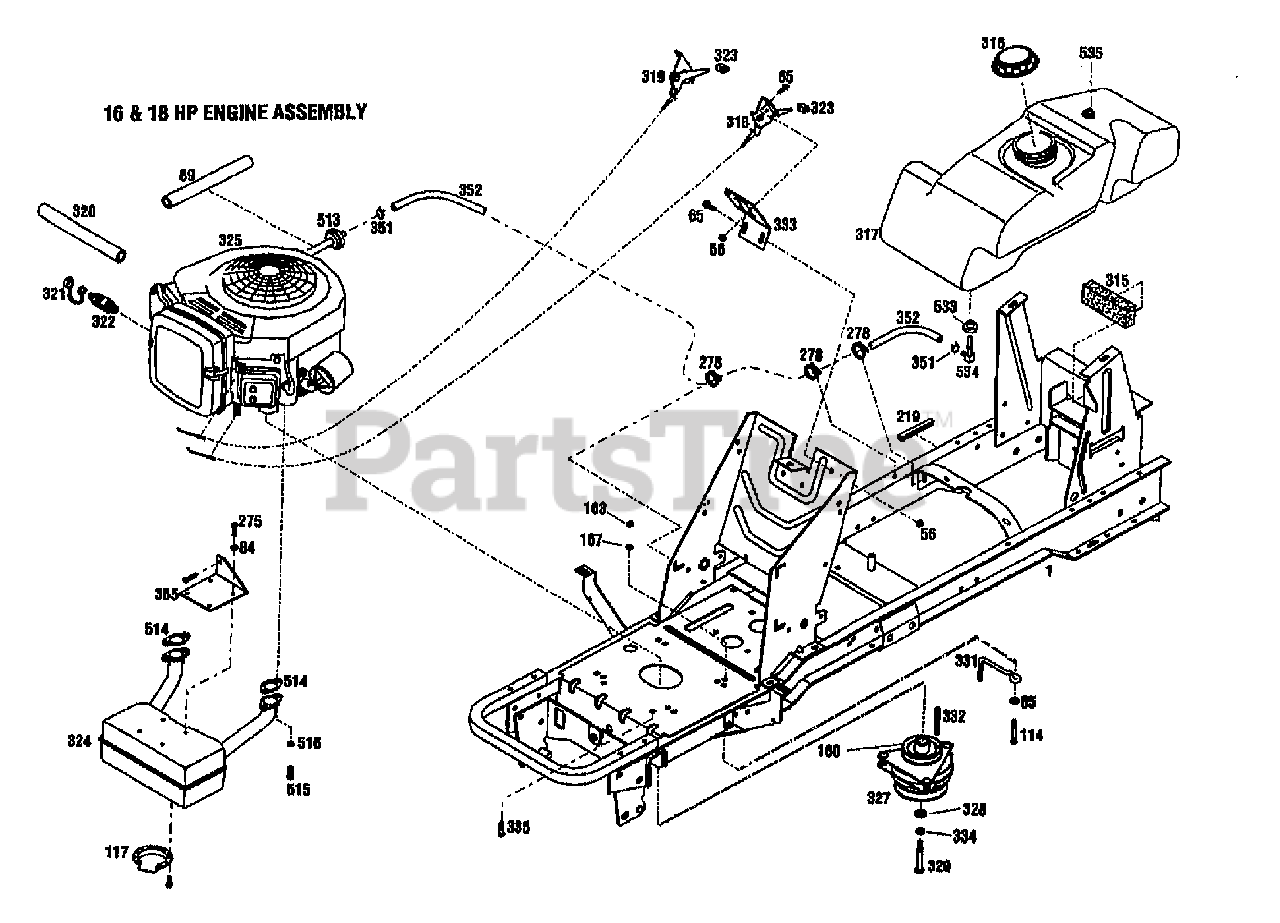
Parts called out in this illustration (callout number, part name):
56	NUT-HF/LK 1/4-20 ZP
84	WASHER-LK .25 ZP
85	WASHER-FLAT 3/8 SAE
89	INSULATION-FUEL LINE
114	SCR-THRD FRM 3/8-16X1.50
117	DEFLECTOR-MUFFLER
160	PULLEY-ENGINE
167	WASHER-LK .375 @ DEPL
275	SCR-HH 1/4-20X.625 G5 ZP
278	TIE-CABLE NYLON BLACK
315	PAD-FUEL TANK
316	CAP-FUEL
317	TANK-FUEL
318	THROTTLE-CONTROL
319	CONTROL-CHOKE
320	HOSE
321	CAP-OIL DRAIN
322	ASSM-OIL VALVE
325	ENGINE 16HP B&S #303777-0333-03 {13039}
325	ENGINE 18HP B&S #350777-0117-01 {13040}
327	CLUTCH-ELECTRIC
328	WASHER-SPEC 1.42X.468X.25 ZP
329	SCR-HH 7/16-20X3.00
331	CLUTCH-RETAINER
332	KEY-.25 SQ X 2.5
333	BRKT-MOUNTING CONTROL
334	WASHER-LK .438 ZP
335	SCR-HH 3/8-16X1.0 THDFM
351	CLAMP-HOSE
352	LINE-FUEL
355	BRKT-MUFFLER
514	MUFFLER GASKET
515	SCR-HH 1/4-20X1.0
516	WASHER-LK .25 ZP
533	BUSHING-RUBBER
534	ELBOW-90 DEG (FUEL LINE)
535	VENT-FUEL TANK
